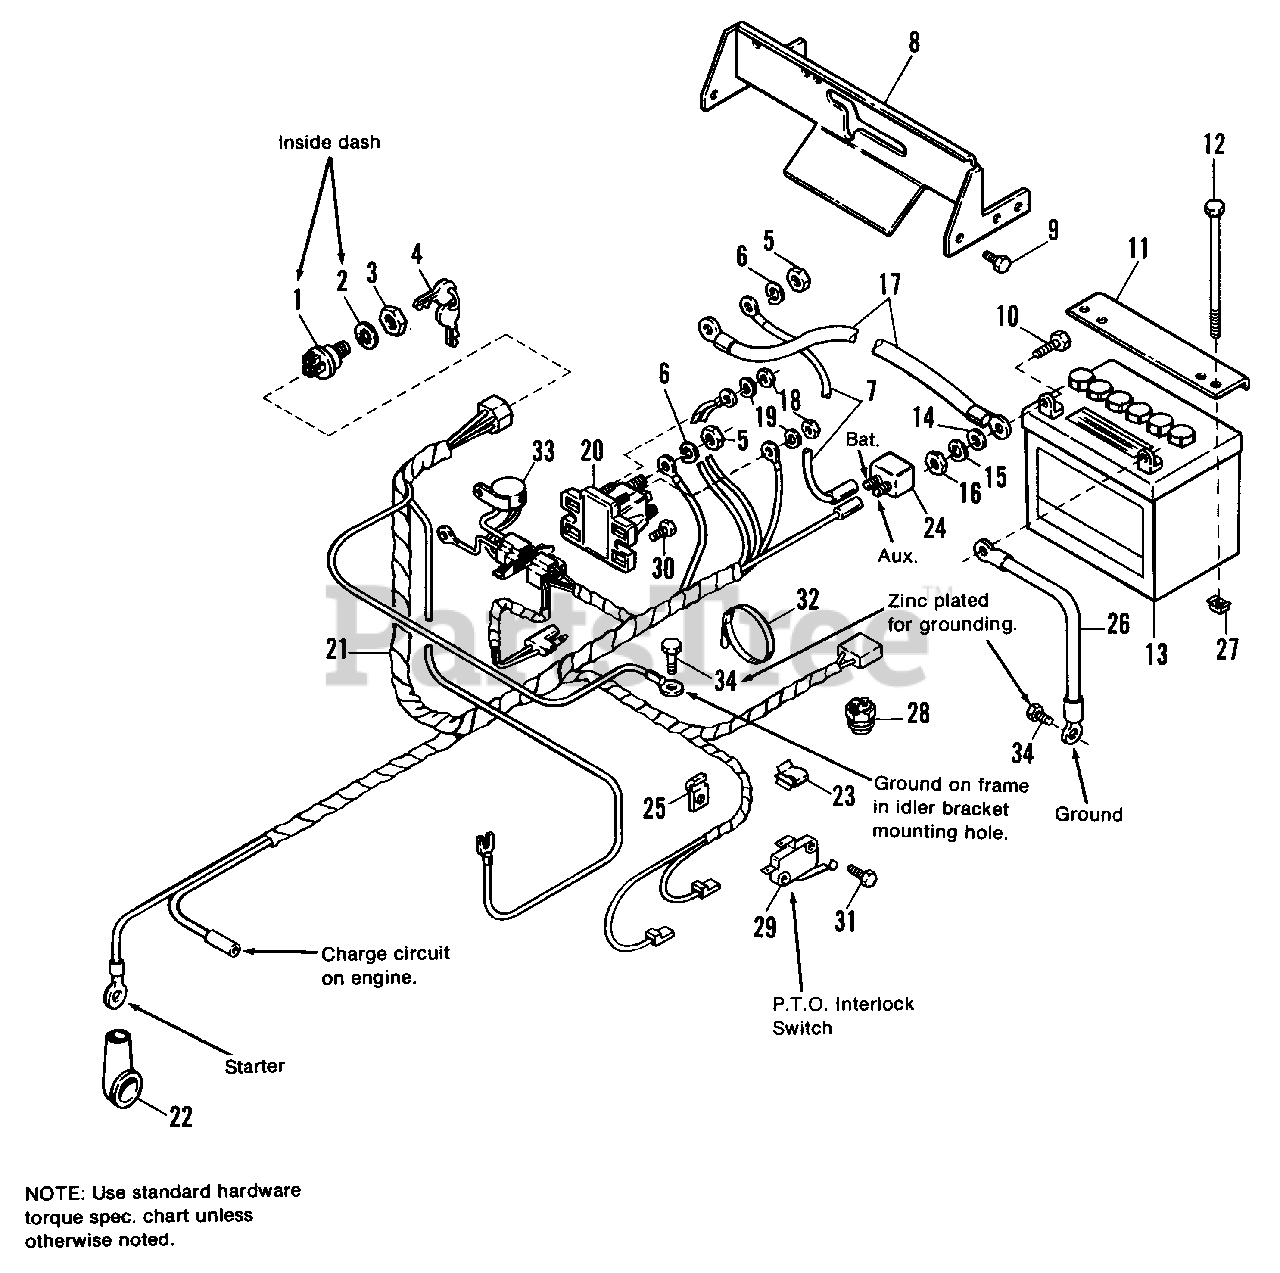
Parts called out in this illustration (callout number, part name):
1	SWITCH, Ignition
2	LOCKWASHER, Internal Tooth, 5/8
3	NUT, 5/8-32
5	NUT, Hex, 5/16-24
6	LOCKWASHER, 5/16
8	QUADRANT, Shift
9	SCREW, Taptite, 1/4-20 x 3/8
10	CAPSCREW, Hex, 1/4-20 x 3/4
11	CLAMP, Battery
12	CAPSCREW, Hex, 1/4-20 x 7
13	BATTERY SERVICE KIT
14	WASHER, 1/4
15	LOCKWASHER, 1/4
16	NUT, Hex, 1/4-20
18	NUT, Hex, #10-32
19	LOCKWASHER, Ext., #10
20	SOLENOID
21	HARNESS, Wiring
22	COVER, Terminal
23	CLIP, Speed
24	CIRCUIT BREAKER
25	CLIP, Wire
27	NUT, Retainer, 1/4-20
28	SWITCH, PTO
29	SWITCH, Interlock
30	SCREW, Taptite, 1/4-20 x 3/4
31	SCREW, Taptite, #5-40 x 3/4
33	MODULE-DSI INTERLOCK
34	SCREW, Taptite, 1/4-20 x 3/8, Zinc Pltd
